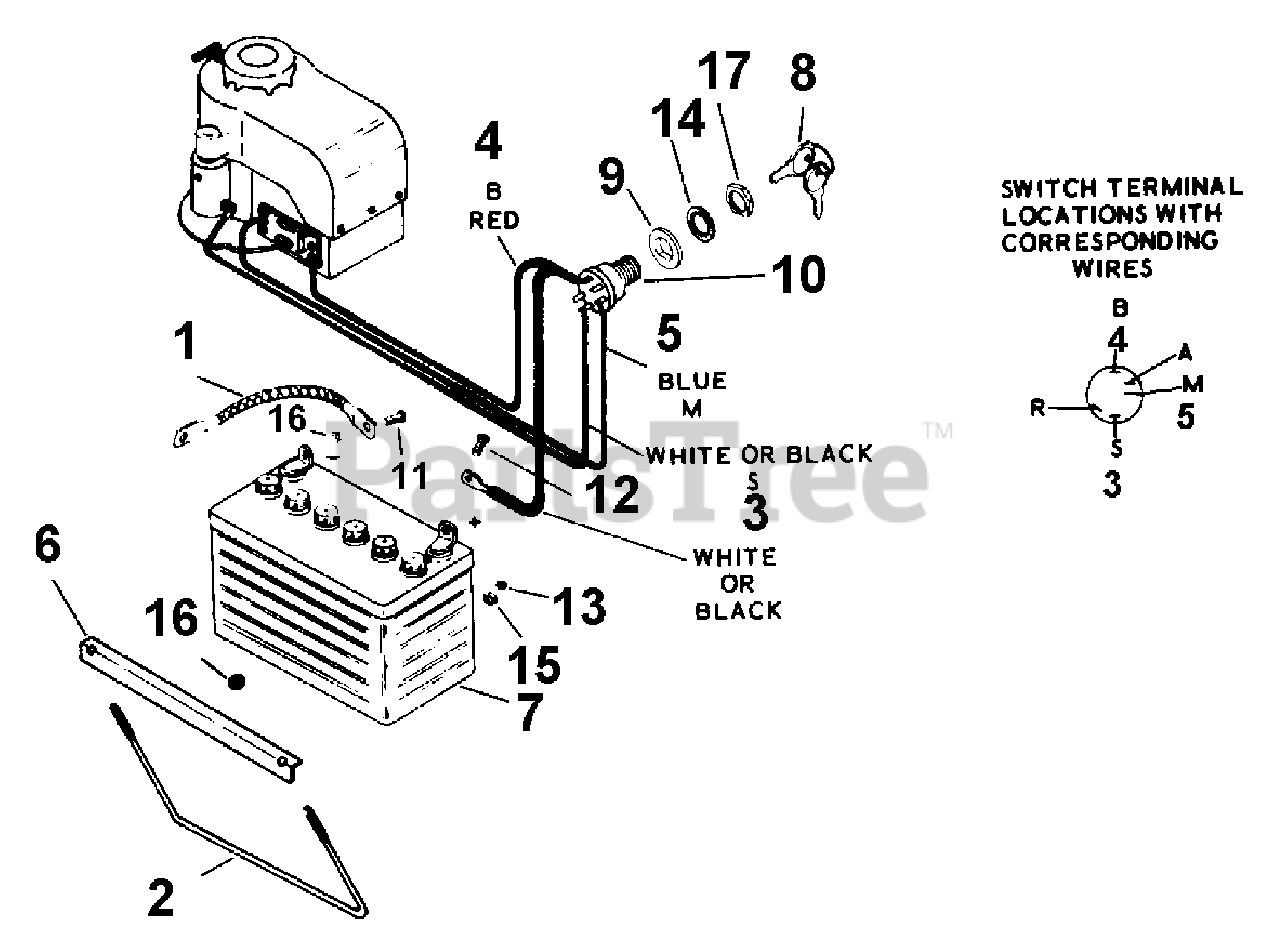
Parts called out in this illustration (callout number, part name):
1	GROUND CABLE
2	BATTERY CLAMP
4	POSITIVE BATTERY CABLE
5	ENG SHORTING WIRE
6	BATTERY HOLD DOWN
7	BATTERY
8	KEYS
10	KEY SWITCH
11	BLT-HEX .25-20X.63 PL GR2
12	BLT-RDHDSQNK .31-18X.75 GR5 PL
13	WSHR-LK .312X.097 PL HVY
14	WSHR-LK-INT .625X.045 PL
15	NUT-HEX .312-18
16	NUT-LK-FLG .250-20 PL
17	NUT-HEX .625-32 PL
